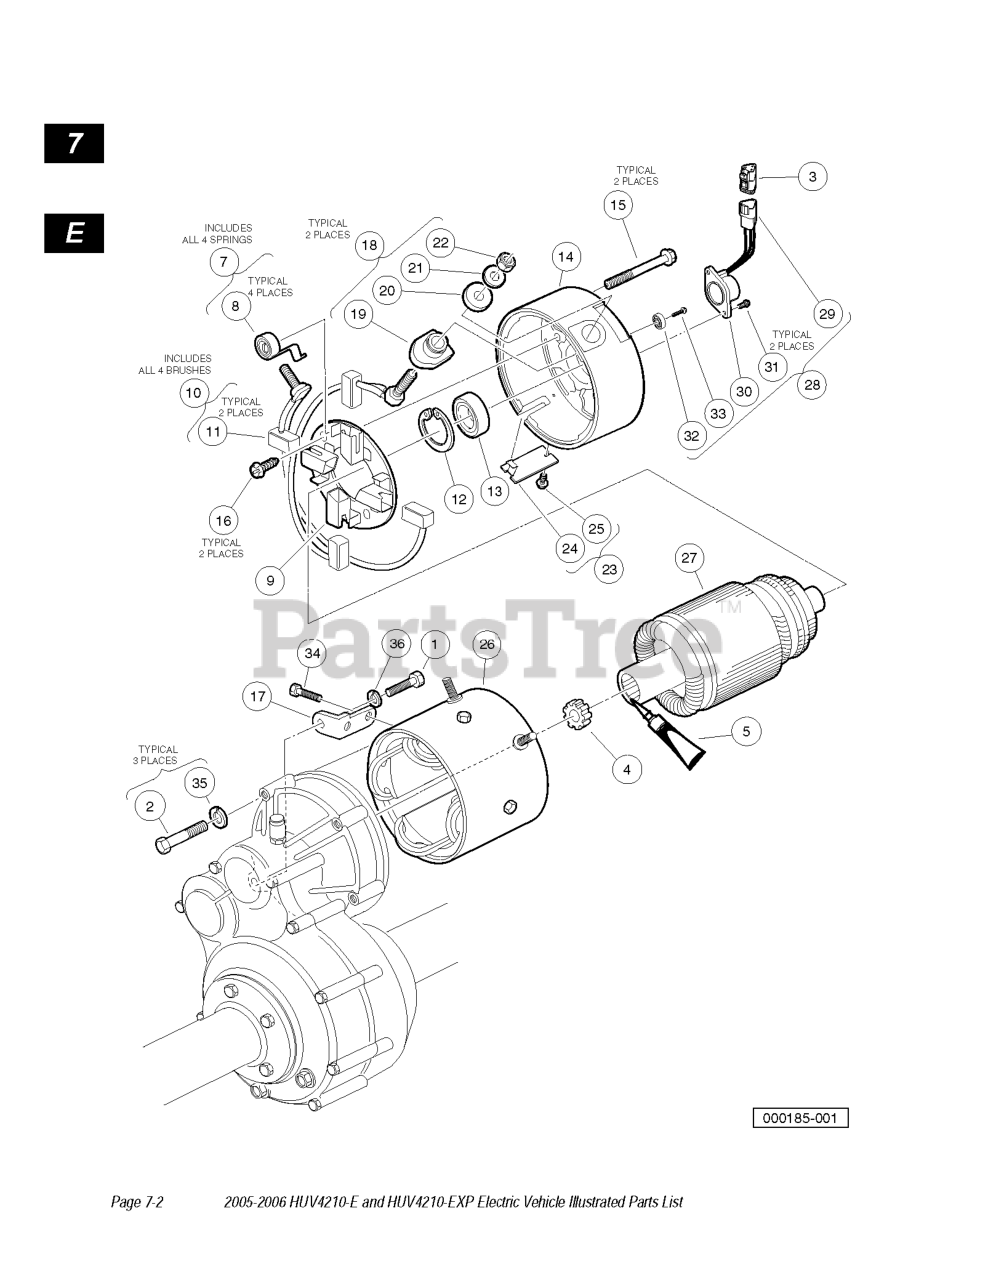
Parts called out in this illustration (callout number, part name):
1	SCREW HEX CAP
2	SCREW, 1/4-20 X 2.25 HEX CAP
3	KIT, 3 PIN PLUG & WEDGE LOCK
4	BUMPER DRIVE UNIT
5	LUBRICANT MOLY TEFLON SINGLE
6	ADC IQ TRAC MOT, 48VDC, 3.3HP
7	SPRING KIT MOTOR BRUSH
9	BRUSH BOX ASSY
10	BRUSH KIT ,MOTOR
12	RING 2.24 INTERNAL RETAINING
13	BEARING MOTOR
14	END CAP, MOTOR
15	Screw, 1/4-20 X 2.25 Hex-Head Washer
16	SCREW 8-32X.5 HX HD TPTITE
17	L-BRACKET MOTOR
18	HARDWARE KIT MOTOR TERMINAL
23	PLATE KIT MOTOR COVER
26	FRAME AND FIELD SERVICE ASM
27	ARMATURE SERVICE ASSM
28	SPEED SENSOR SERVICE PACKAGE
29	KIT 3PIN RECEPT AND WEDGE LOCK
35	LOCKWASHER, 1/4 HELICAL SPLIT
36	LOCKWASHER, 5/16 SPLIT
